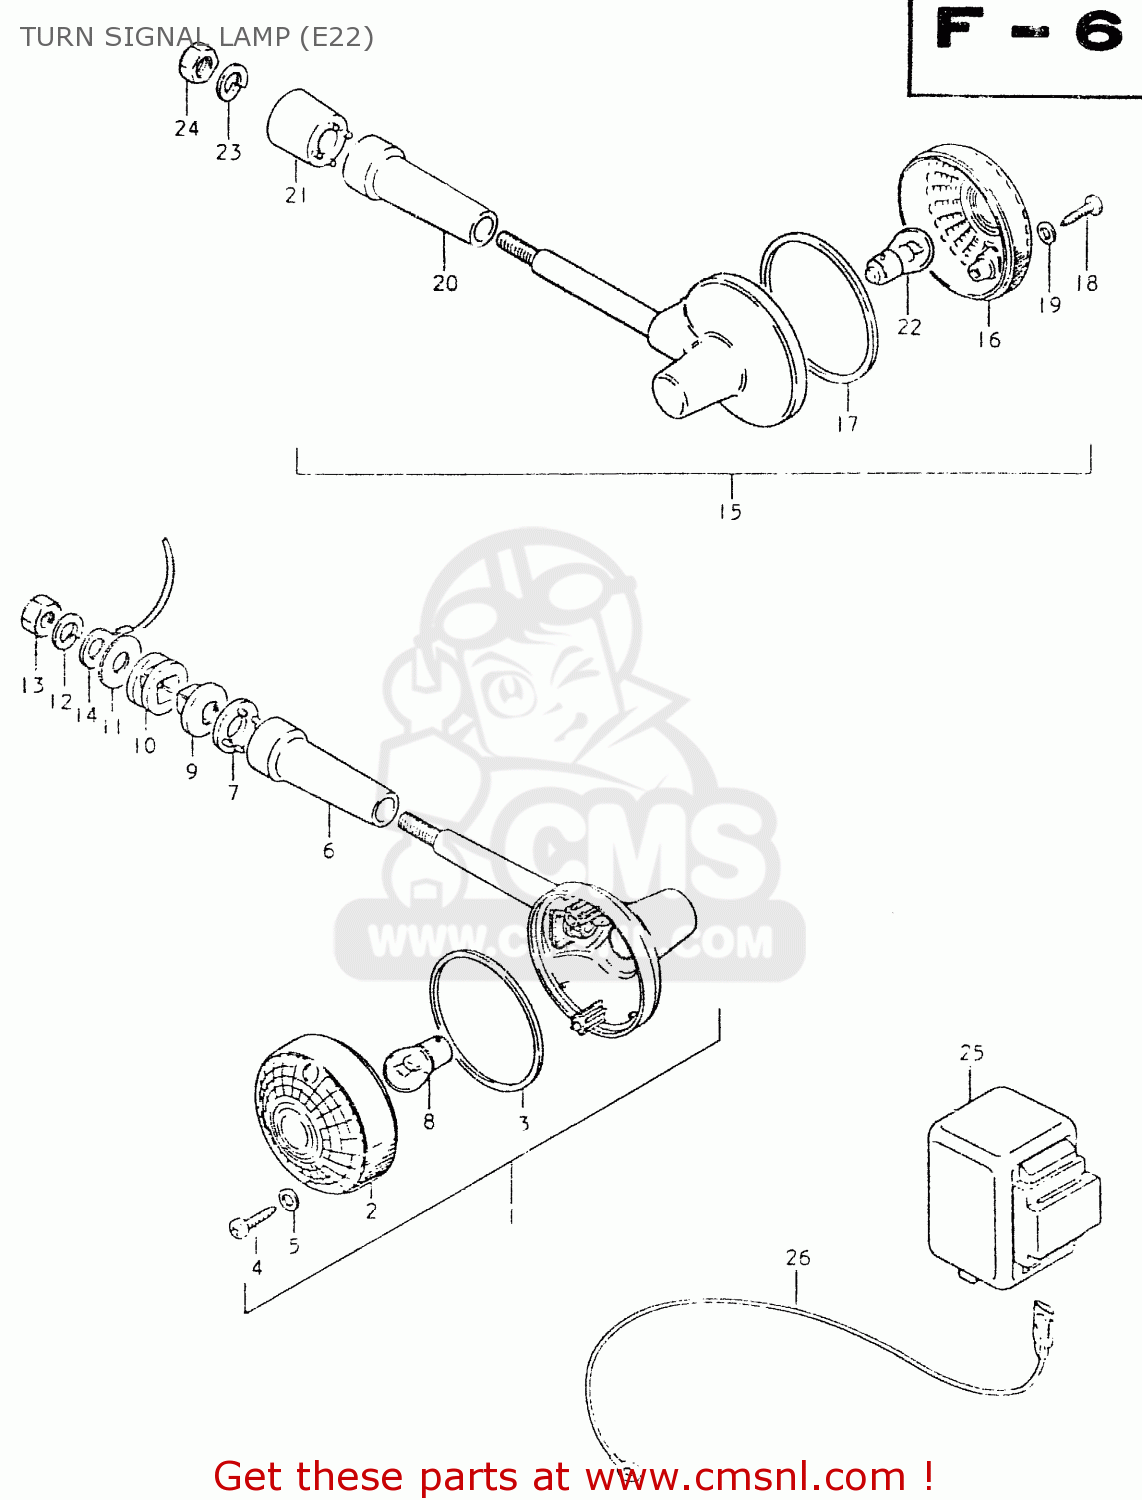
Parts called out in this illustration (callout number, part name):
1	LAMP ASSY,FR T
2	LENS
3	GASKET (NAS)
4	SCREW 4X25
5	GASKET (NAS)
6	COVER,STAY
7	CUSHION
8	BULB(12V21W)
9	SPACER
10	CUSHION
11	WASHER (10.5X30X2.3)
12	LOCK WASHER
13	NUT
14	WIRE
15	LAMP ASSY,RR T
16	LENS
17	GASKET (NAS)
18	SCREW 4X25
19	GASKET (NAS)
20	COVER,STAY
21	CUSHION
22	BULB(12V21W)
23	LOCK WASHER
24	NUT
25	RELAY, TURN SIGNAL
26	LEAD WIRE, RELAY EARTH
